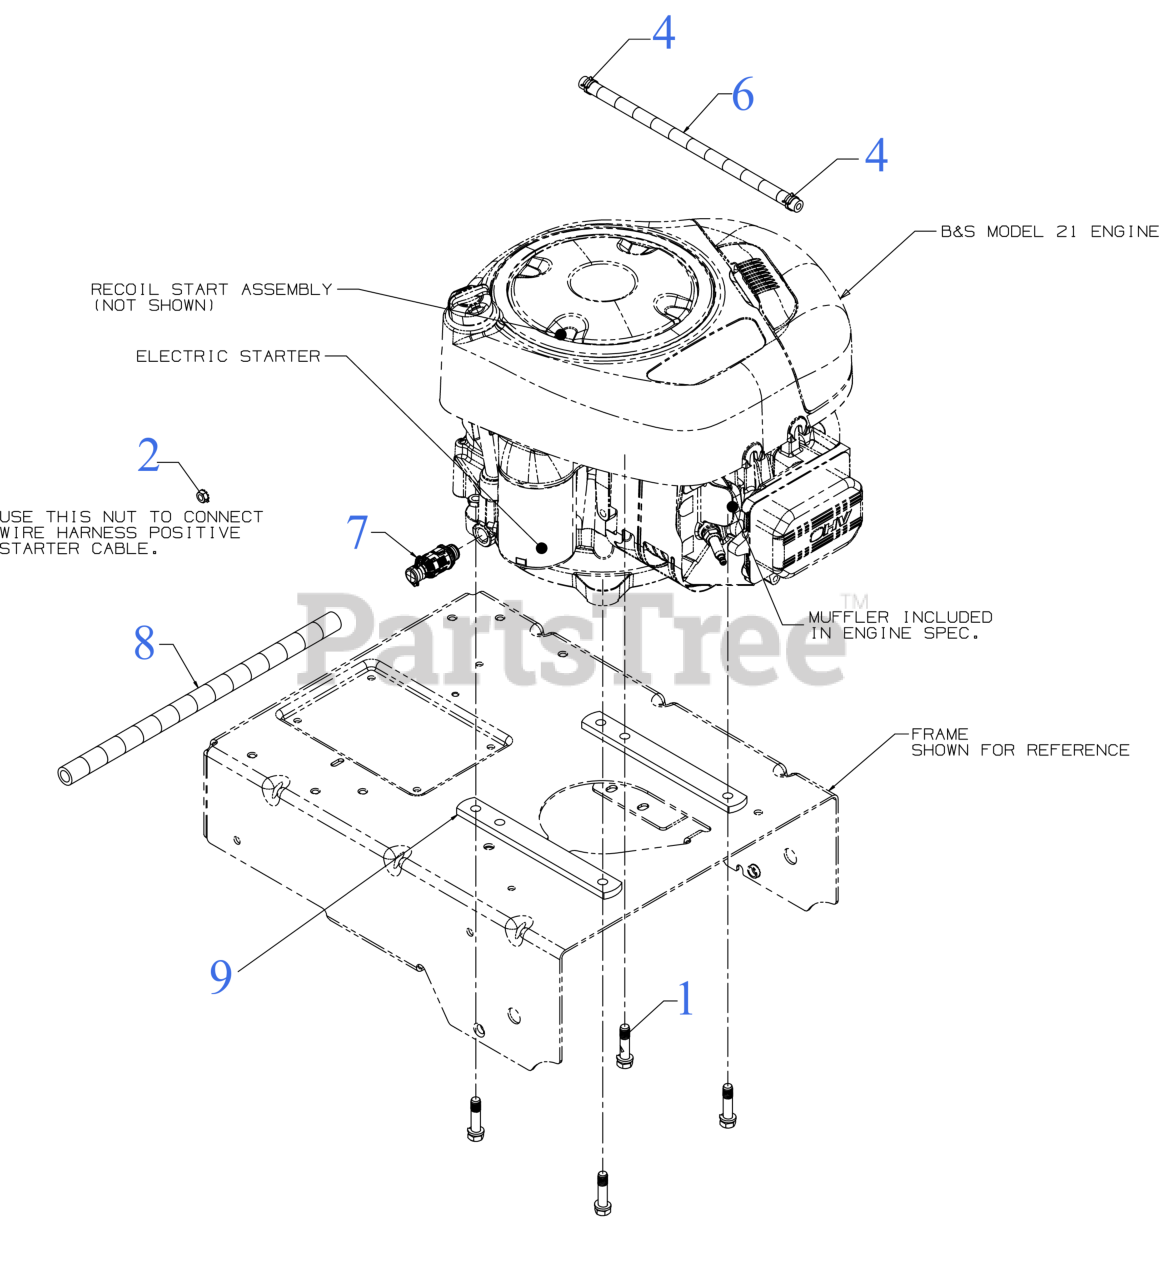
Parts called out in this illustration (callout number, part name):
1	SCREW 3/8-16 x 1.75
1	SCREW 3/8-16 x 1.500
2	SEMS NUT 1/4-20
4	HOSE CLAMP 1/20
6	FUEL HOSE LOW PERMEATION 13"
7	OIL DRAIN VALVE
8	DRAIN HOSE 14''
